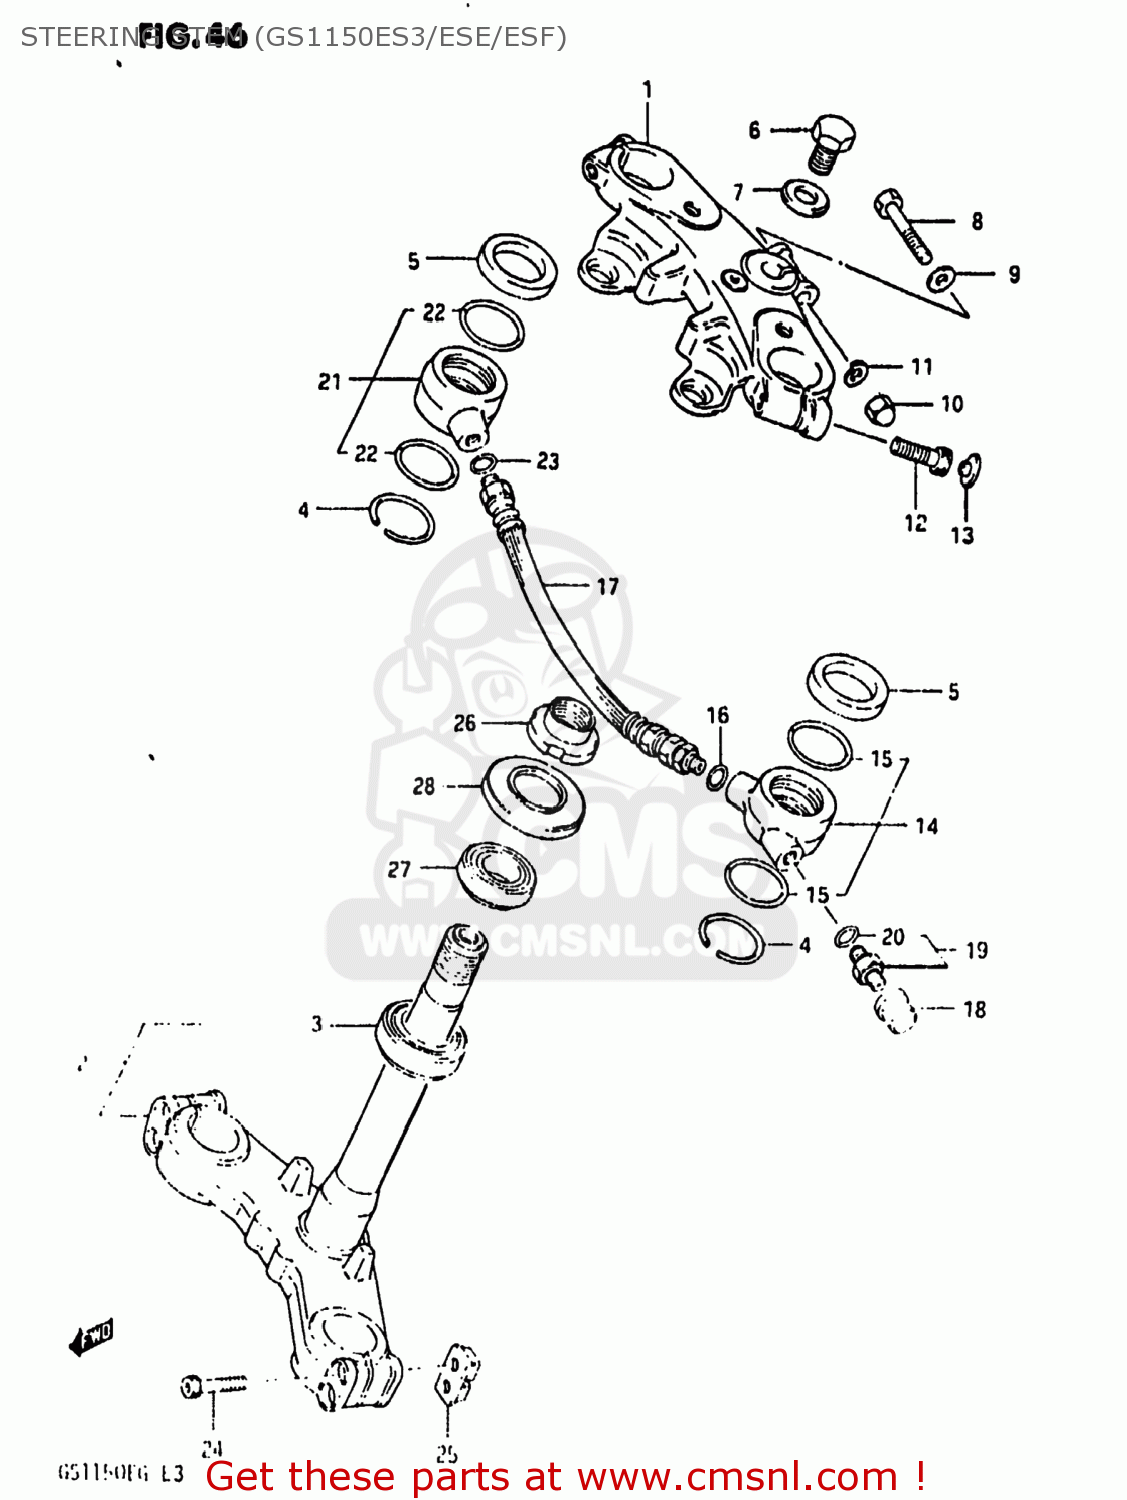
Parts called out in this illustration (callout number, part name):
1	HEAD,STEERING STEM
2	STEM,STEERING
3	BEARING
4	SNAP RING
5	GASKET
6	NUT,STEM HEAD
7	WASHER,STEERING STEM
8	BOLT
9	WASHER
10	NUT,M8X1.25X12
11	WASHER,LOCK,8.
12	BOLT,FORK INNER TUBE FITTING
13	CAP(OD:20)
14	JOINT,AIR,LEFT
15	O RING
16	O-RING
17	JOINT,AIR TUBE
18	CAP,FRONT FORK AIR VALVE
19	VALVE,FRONT FORK AIR
20	O-RING
21	JOINT,AIR,RIGHT
22	O RING
23	O-RING
24	BOLT 8X45
25	NUT,FR FORK INNER TUBE
26	NUT,STEERING STEM
27	TAPER,ROLLER BEARING
28	DUST SEAL,STEERING UPR
